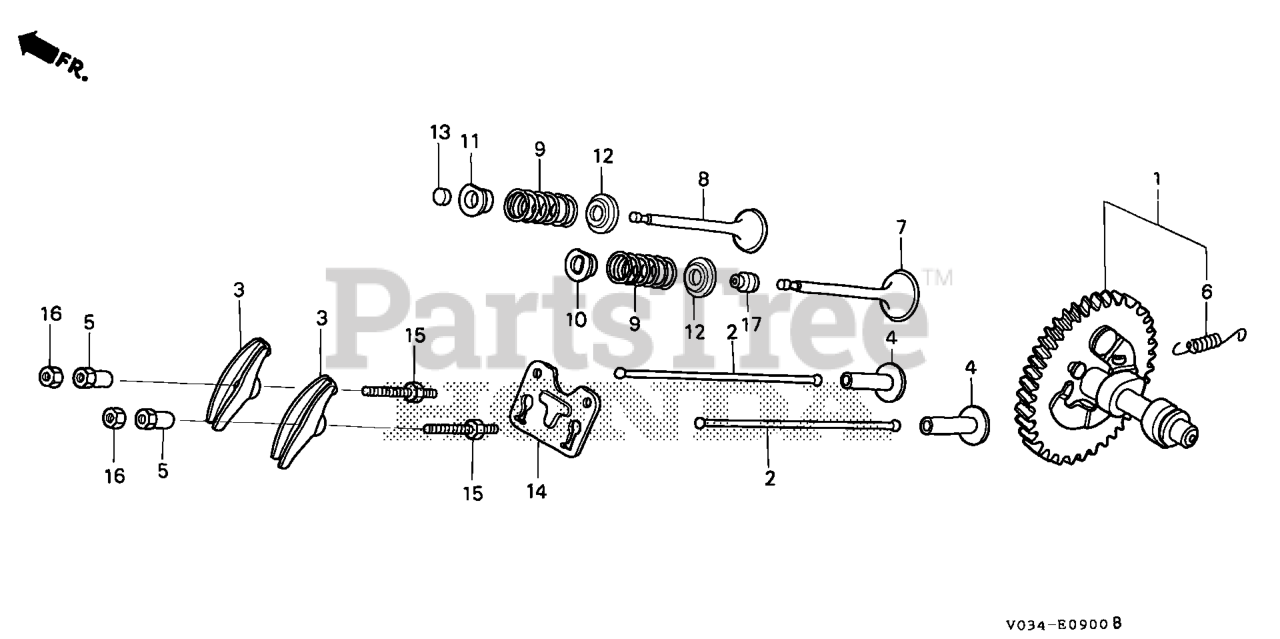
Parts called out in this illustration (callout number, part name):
1	CAMSHAFT ASSY.
2	ROD, PUSH
3	ARM, VALVE ROCKER
4	LIFTER, VALVE
5	PIVOT, ROCKER ARM
6	SPRING, WEIGHT RETURN
7	VALVE, IN.
8	VALVE, EX.
9	SPRING, VALVE
10	RETAINER, IN. VALVE SPRING (EXHAUST SIDE)
11	RETAINER, EX. VALVE SPRING
12	SEAT, VALVE SPRING
13	ROTATOR, VALVE
14	PLATE, PUSH ROD GUIDE
15	BOLT, PIVOT (8MM)
16	NUT, PIVOT ADJ.
17	SEAL, VALVE STEM
